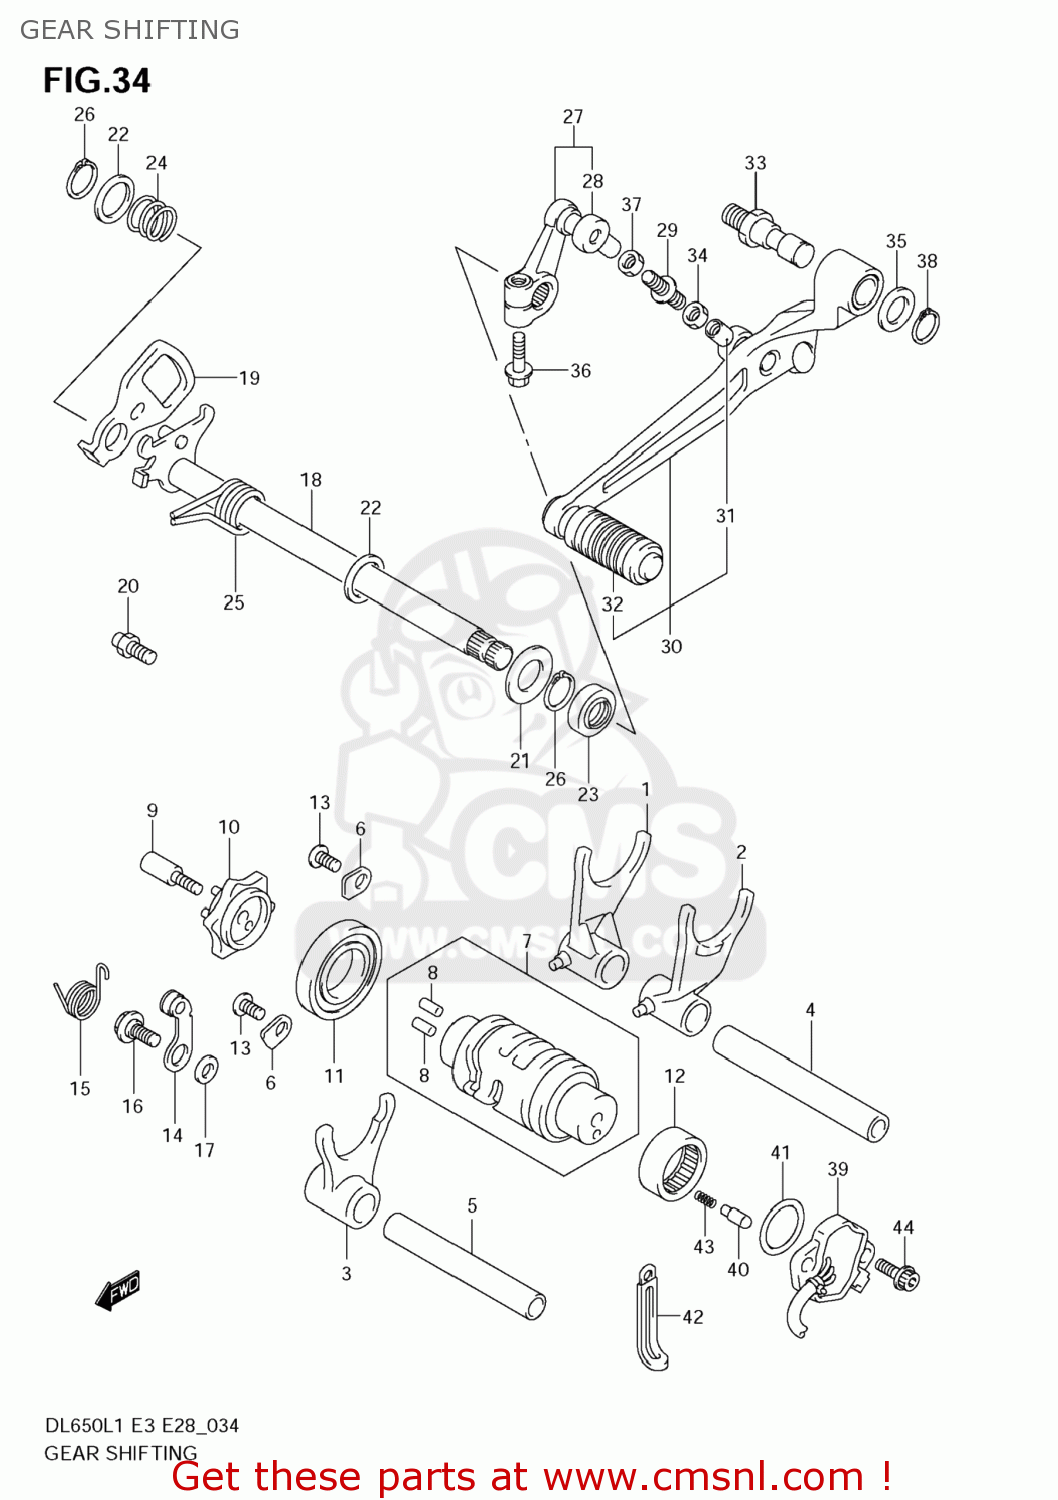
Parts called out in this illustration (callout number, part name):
1	FORK,GEAR SHIFT NO.1
2	FORK,GEAR SHIFT NO.2
3	FORK,GEAR SHIFT NO.3
4	SHAFT,GEAR SHIFT FORK
5	SHAFT,GEAR SHIFT FORK NO.1
6	RETAINER
7	CAM,GEAR SHIFT
8	PIN
9	BOLT,GEAR SHIFT CAM PLATE
10	PLATE,GEAR SHIFT CAM
11	BEARING(25X47X8)
12	BEARING(25X32X12)
13	SCREW
14	STOPPER,SHIFT CAM
15	SPRING,SHIFT
16	BOLT(6X14.3)
17	WASHER
18	SHAFT,GEAR SHIFT
19	PLATE,GEAR SHIFT CAM DRIVE
20	STOPPER,GEAR SHIFT ARM
21	WASHER(14X29X0.8)
22	SHIM(14X22X1)
23	SEAL,OIL(14X22X7.3)
24	SPRING
25	SPRING
26	CIRCLIP
27	ARM,GEAR SHIFT LINK
28	COVER,DUST
29	ROD,GEAR SHIFT LINK
30	LEVER ASSY,GEA
31	COVER,DUST
32	RUBBER,GEAR SHIFT PEDAL
33	SHAFT,GEAR SHIFT LEVER
34	NUT
35	WASHER(12.5X20X1)
36	BOLT
37	NUT
38	CIRCLIP
39	BASE ASSY,GEAR SHIFT TERMINAL
40	PIN(5X15.5)
41	O RING(D:2.4,ID:26.2)
42	CLAMP(L:80)
43	SPRING
44	BOLT
